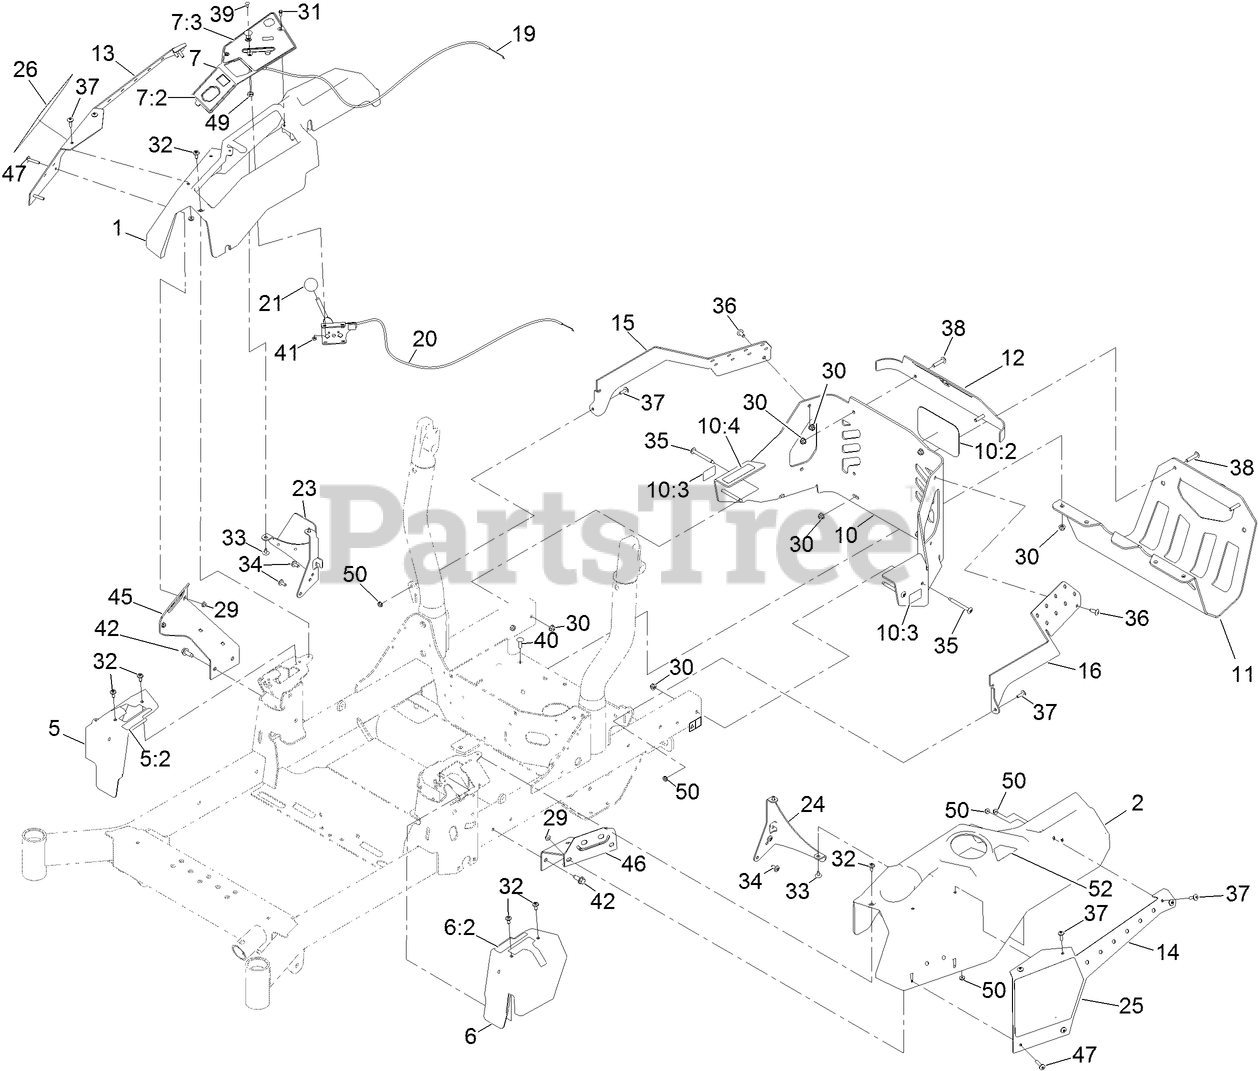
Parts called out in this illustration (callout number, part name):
1	CONSOLE-RH
2	CONSOLE-LH
5	COVER-CONTROL, MOTION (RH)
5:2	DECAL-CONTROL, MOTION (RH)
6	COVER-CONTROL, MOTION (LH)
6:2	DECAL-CONTROL, MOTION (LH)
7	CONTROL PANEL ASM
7:2	DECAL-PANEL, CONTROL
7:3	DECAL-PANEL, CONTROL
10	REAR GUARD ASM
10:2	DECAL
10:3	DECAL-WARNING
10:4	DECAL-ARRESTOR, SPARK
11	GUARD-MUFFLER
12	TRIM-UPPER REAR
13	COVER,POD RH
14	COVER [BLACK]
15	BRACKET-GUARD, RH
16	BRACKET-GUARD, LH
19	CABLE-CONTROL, CHOKE
20	CABLE-CONTROL, THROTTLE
21	KNOB-BALL
23	SUPPORT-CONSOLE, RH
24	BRACKET-CONSOLE, LH
25	DECAL-2000, LH
26	DECAL-2000, RH
29	NUT-HF
30	NUT-HF, NI
31	SCREW-HWH
32	SCREW-SHOULDER
33	SCREW-TORX
34	SCREW-TORX
35	SCREW-TORX
36	SCREW-TORX
37	SCREW-TRUSS
38	SCREW-TORX
39	BOLT-CARR
40	SCREW-CARR
41	NUT-LOCK, NI
42	SCREW-FORMING, THREAD
45	BRACKET-SUPPORT, POD (RH)
46	BRACKET-SUPPORT, POD (LH)
47	SCREW-TRUSS
49	NUT-HJ
50	NUT-KEPS
52	DECAL-FILL, FUEL
